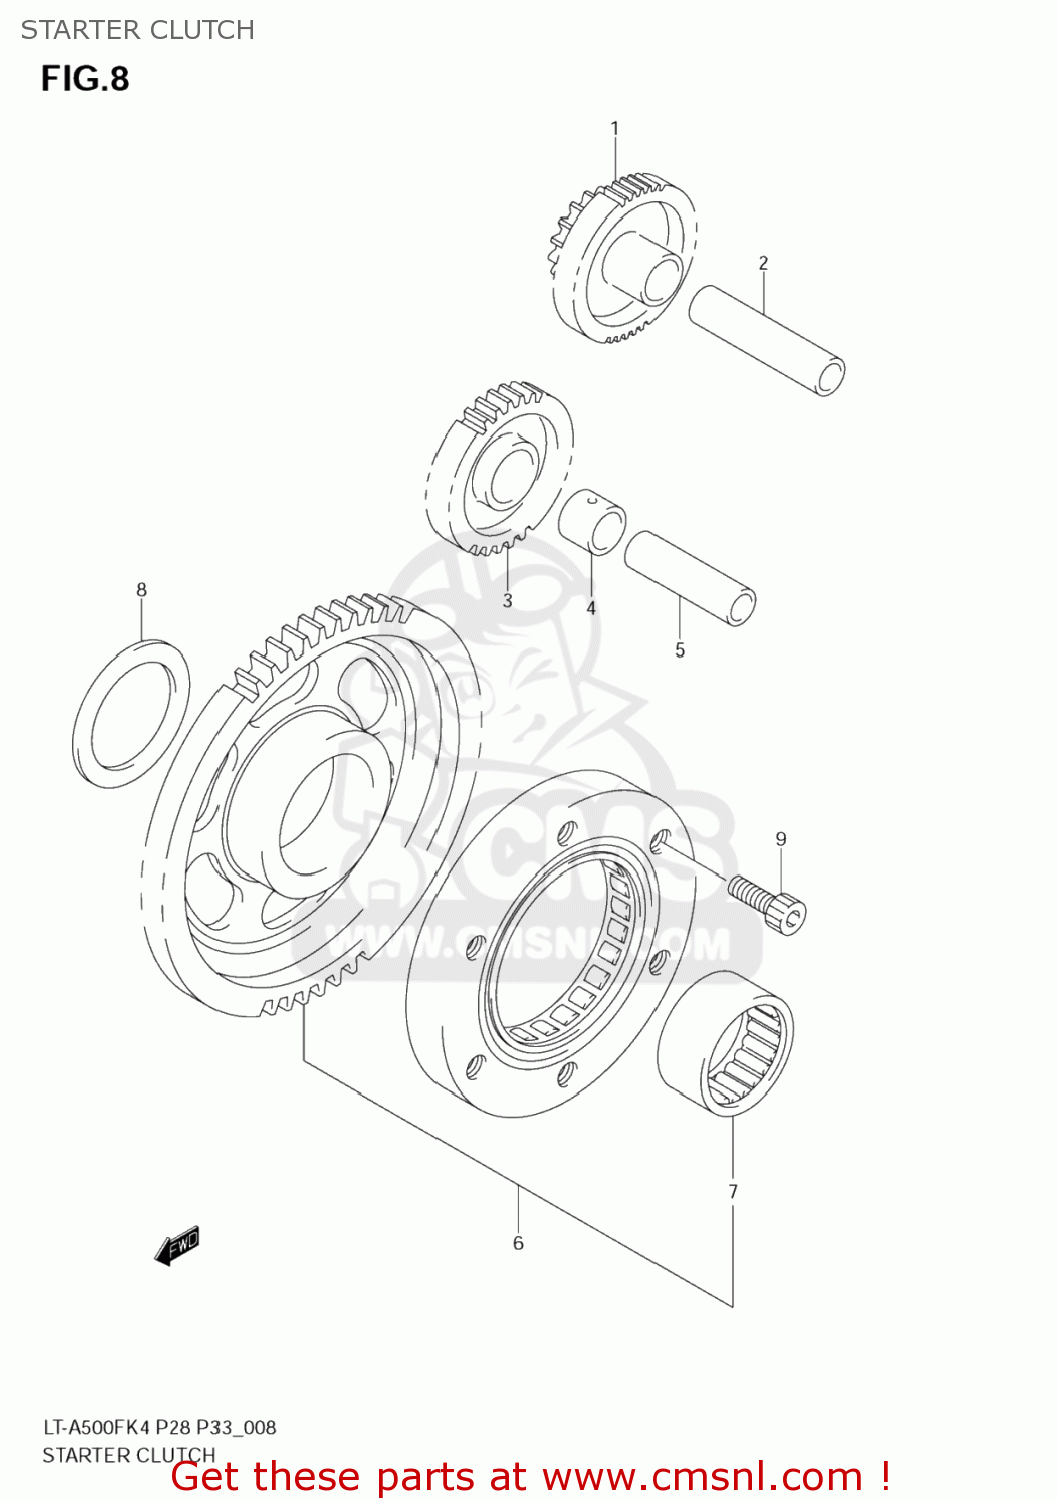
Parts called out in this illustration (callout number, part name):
1	GEAR,STARTER IDLE NO.1
2	PIN(8X12X59)
3	GEAR,STARTER IDLE NO.2
4	SPACER(12.2X20X14)
5	PIN(8X12X45.5)
6	CLUTCH SET,STARTER
7	BEARING(31X39X17.8)
8	WASHER
9	BOLT(8X20)
